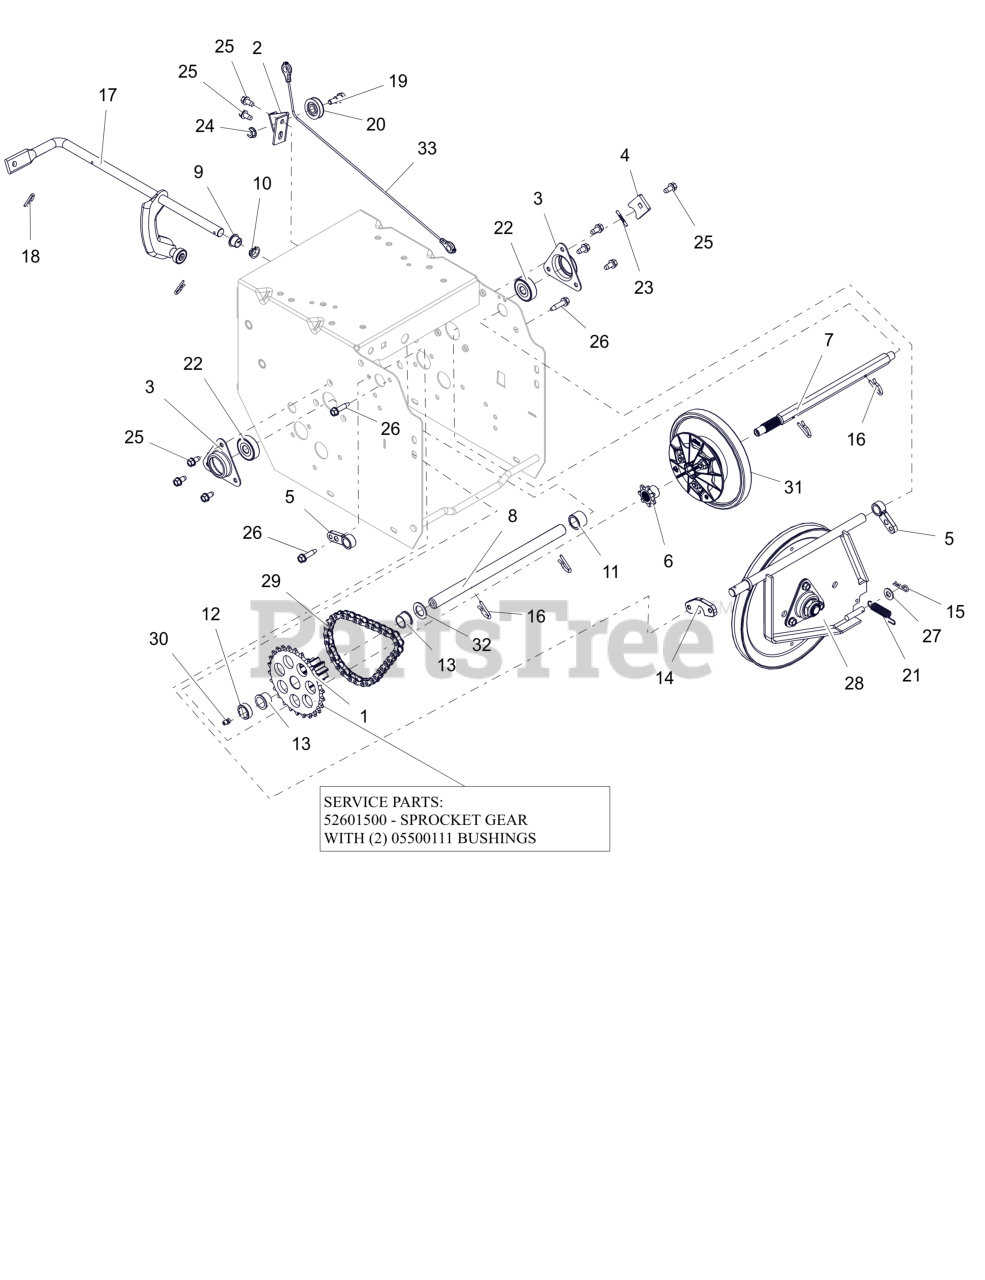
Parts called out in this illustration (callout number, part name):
1	PINION & SPROCKET
1	PINION & SPROCKET W/BUSHINGS
2	BRACKET, CABLE PULLEY
3	FLANGE, BEARING
4	TAB, ANTI ROTATION
5	SUPPORT BUSHING, SWING GATE
6	SPROCKET, PINION 7T W/SPLINE
7	SHAFT, HEX W/SPLINE TRACK
8	SHAFT, PINION TRACK
9	BUSHING, POLYLINER-.50 SPLIT
10	BUSHING, POLYLINER-.50 SNAPIN
11	SPACER, .635X.880X.611
12	BSHG-SLV, .635X.880X.305
13	BSHG-FLG .625X.750X.500X.875
14	SPACER, SWING GATE
15	PIN, HAIR #213 .08X1.19 ZCC
16	PIN, SPRING CLIP
17	ARM, SHIFT-SMALL DASH (ASSY)
18	CLIP, SPRING
19	BOLT, SHLDR -.375 X .375 X .25-20
20	PULLEY, CABLE
21	SPRING, EXT. .043X.438X1.64
22	BRG-BALL .437X1.375X.437
23	@PIN-GRV .125X1.00 TP E ALLOY
24	NUT-LK-CTR-FLG .25-20 ZC120
25	SCR-TAP .25-20X.50 HWH ZCC
26	SCR, TAP .25-20X1.00 TT2000 ZCC
27	WSHR,FLT .344X.688X.065 ZCC
28	PLATE, SWING - ASSEMBLY
29	CHAIN - #41, 32 PITCHES
30	ZERK,FITTING .25X.125 DRIVE IN
31	DISC, FRICTION DRIVE-ASSEMBLY
32	WSHR, FLT .630X1.005X.062 ZCC
33	CABLE, LOWER TRACTION (CMPCT)
